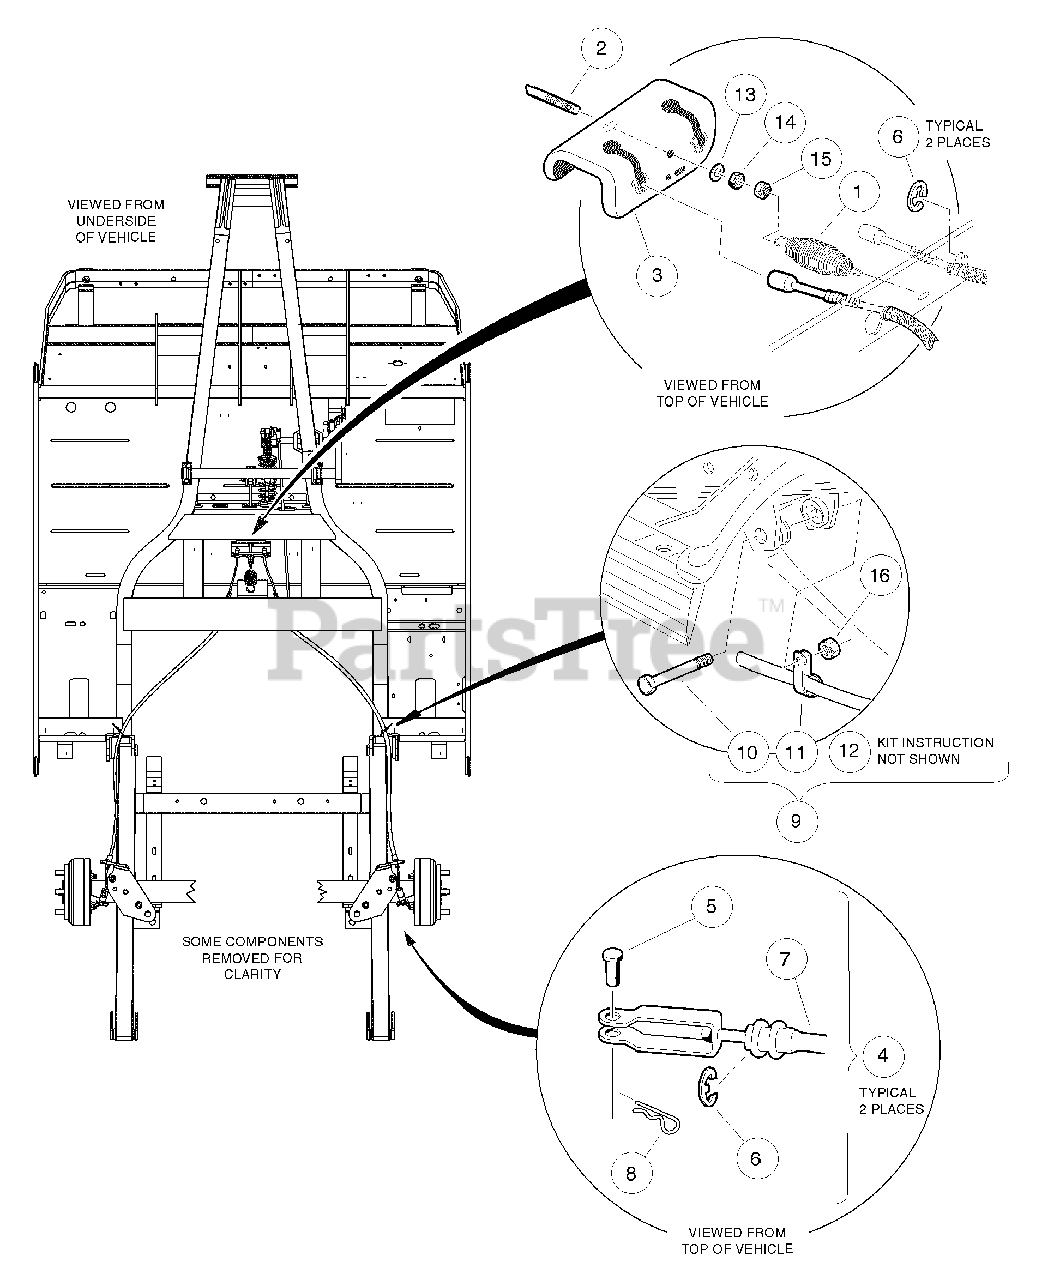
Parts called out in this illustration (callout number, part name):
1	Spring, Brake Return
2	Rod, Equalizer
3	Equalizer Bracket
4	Brake Cable Kit
5	Pin, Clevis, 5/16 X 3/4
6	E-Glip, 1/2
7	Cable, Brake
8	Pin, 3/32 X 1.00 Sq Cut Cotter
9	Kit, Field P-clamp, Brake Line
10	Screw, 3/8-16 X 3.50 Hex Cap
11	P-clamp, Brake Line
12	Instr Fd. P-clamp, Brake Line
13	Washer, 5/16 Type A Flat
14	Nut, 5/16-18 Hex
15	Locknut, 5/16-18 Nylon Insert
16	Locknut, 3/8-16 Hex
